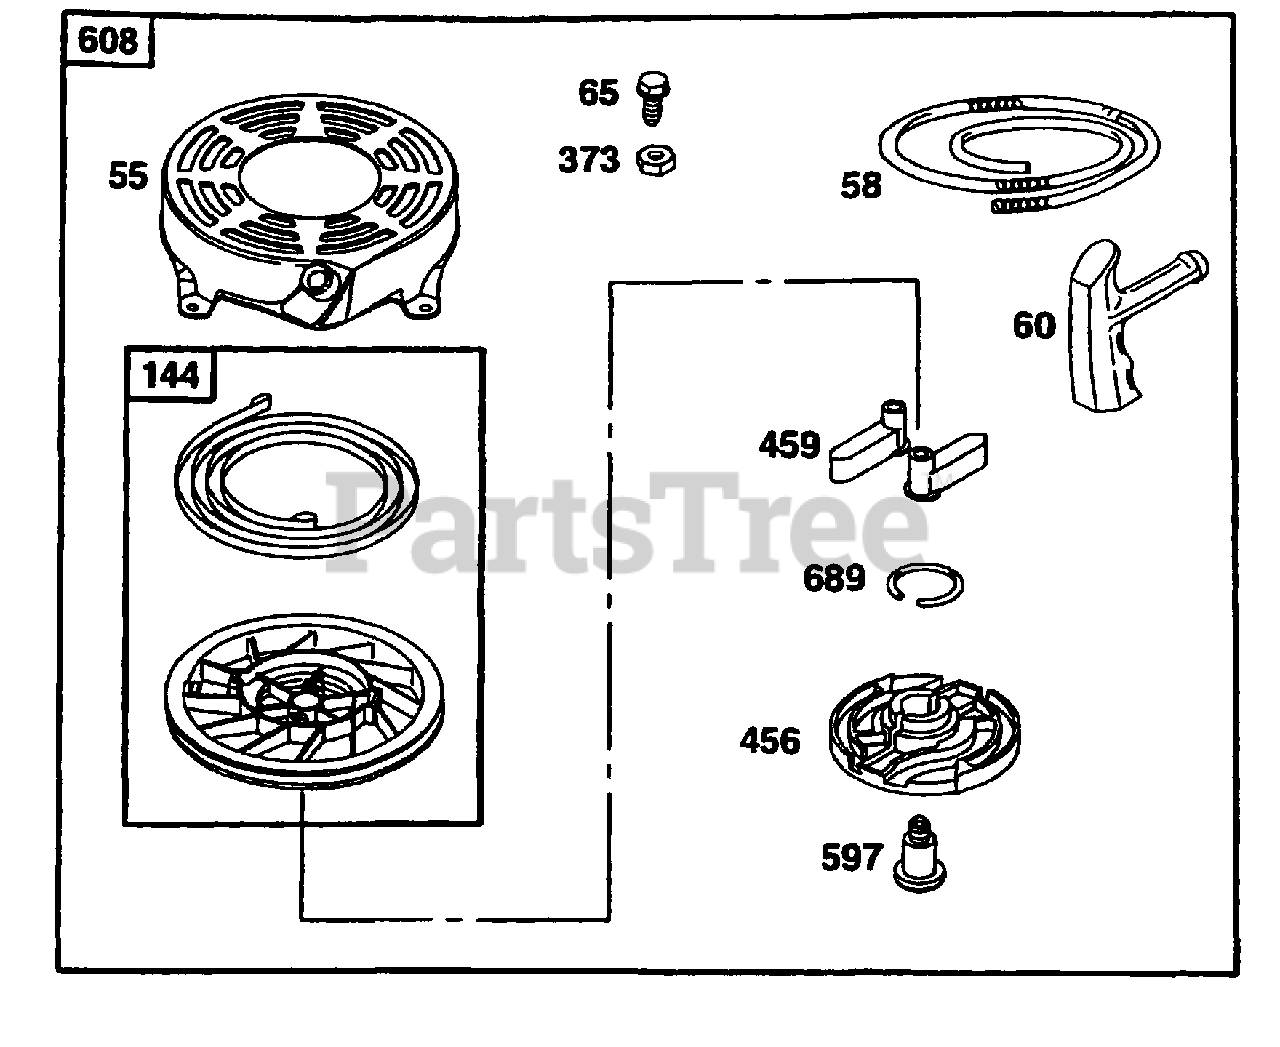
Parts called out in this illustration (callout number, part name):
55	Rewind Starter Housing
58	Starter Rope (Cut To Required Length)
60	Starter Rope Grip
65	Hex Screw
144	Starter Pulley
373	Hex Nut
456	Spring Retainer
459	Paul
597	Shoulder Screw
608	Rewind Stater Assembly
689	Friction Spring
